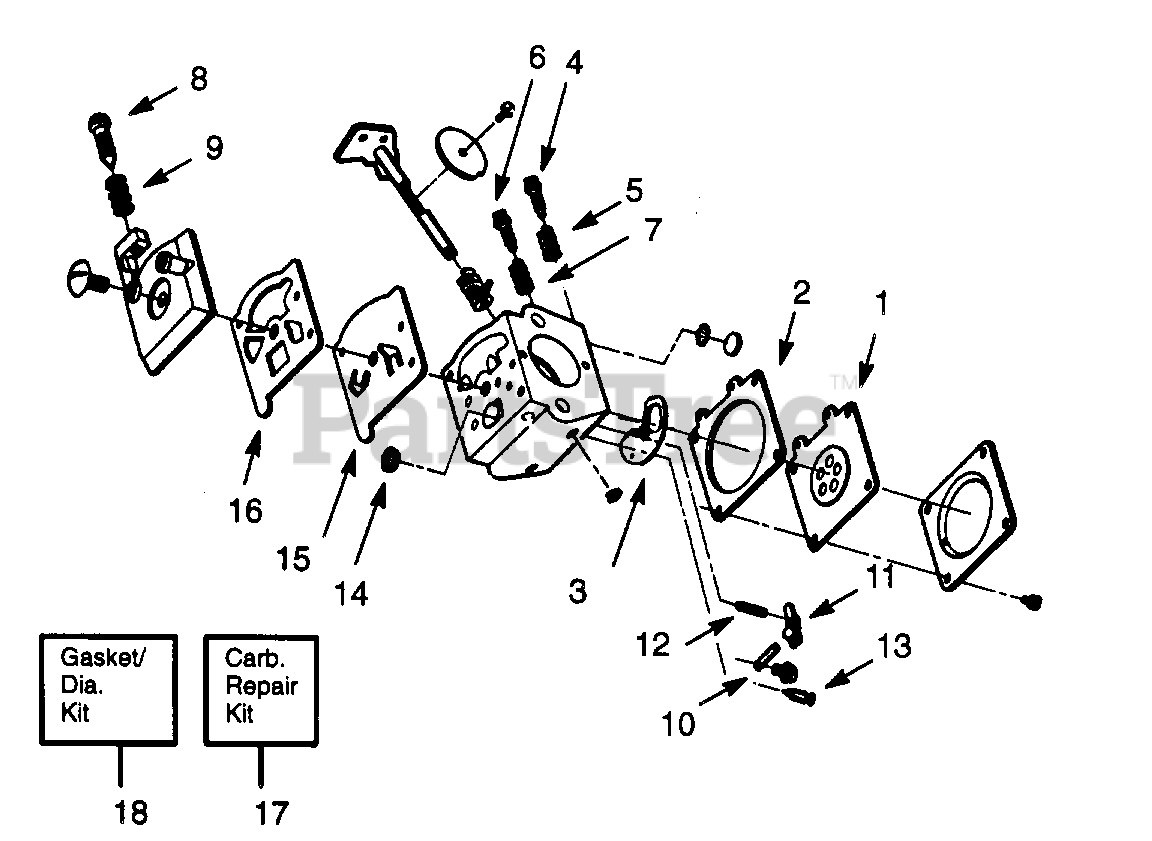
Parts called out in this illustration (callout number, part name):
1	Metering Diaphragm
2	Metering Diaphragm Gasket
3	Circuit Plate Gasket
4	Hi Speed Needle
5	Hi Speed Needle Spring
6	Idle Needle
7	Idle Needle Spring
8	Idle Speed Screw
9	Idle Speed Spring
10	Metering Lever Pin
11	Metering Lever
12	Metering Lever Spring
13	Inlet Needle Valve
14	Inlet Screen
15	Pump Diaphragm
16	Pump Gasket
17	Carb. Kwik Repair Kit
18	Carb. Gasket/Diaphragm Kit
